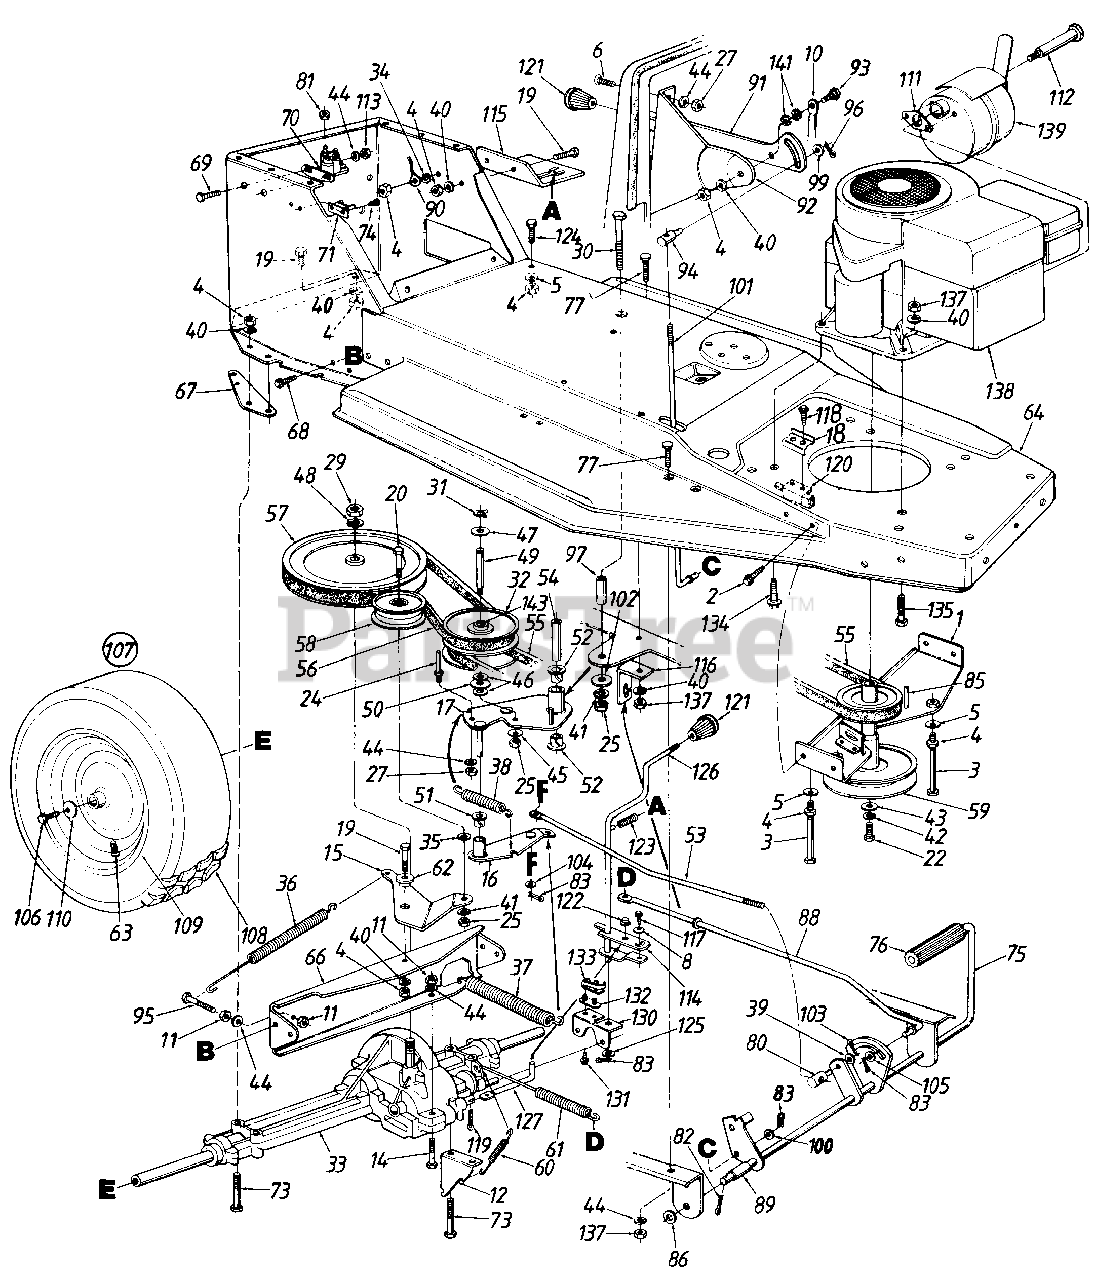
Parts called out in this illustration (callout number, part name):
1	Engine Pulley Belt Guard Ass'y.
2	Hex AB-Tap Scr. 1/4 x .62"
3	Hex Bolt 5/16-18 x 51/4" Lg.
4	Hex Nut 5/16-18 Thd.
5	Bell-Wash. .345" I.D. x .88
6	Truss-Mach. Scr. 1/4-20 x .50" Lg.
8	Bell-Wash. .265" I.D. x .75
10	Speed Selector Brace
11	Hex Nut 1/4-28 Thd.*
12	Spring Retainer Brkt.
14	Hex Bolt 1/4-28 x 1.75" Lg.
17	Variable Speed Brkt. Ass'y.
18	Switch Plate
19	Hex Bolt 5/16-18 x .75" Lg.
20	Hex Bolt 3/8-24 x 2.0" Lg. Grade 5
22	Hex Bolt 7/16-20 x 1.5" Lg.
24	Belt Guard Pin
25	Hex Nut 3/8-24 Thd.
27	Hex Nut 1/4-20 Thd.
29	Hex Jam Nut 1/2-20 Thd.
30	Hex Bolt 3/8-24 x 3.75" Lg.
31	Snap Ring
32	Variable Speed Pulley Ass'y.
33	Transaxle Complete
34	Ext. L-Wash. 5/16" I.D.
35	Fl-Wash. 3/8" I.D. x 1.0" O.D.
36	Extension Spring 6.12" Lg.
37	Extension Spring 7.5" Lg.
38	Extension Spring 2 69" Lg.
39	Fl-Wash. 885" I.D. x .620"
40	L-Wash. 5/16" I.D.
41	L-Wash. 8/8" I.D.
42	L-Wash. 7/16" I.D.
43	Fl-Wash. .450" I.D. x 1.25"
44	L-Wash. 1/4" I.D.
45	Bell-Wash. .39" I.D. x 1.13"
46	Fl-Wash. 56" I.D. x 1.0" O.D.
47	Washer "Teflon" .565 I.D.
48	Bell-Wash. 1/2" I.D. x 1.0" O.D.
49	Shaft .56" Dia. x 8 .375" Lg.
50	Thrust Brg. 1.25 O.D.
51	Flanged Nyliner Brg.
52	Nyliner Flanged Brg.
53	Speed Control Rod
54	Spacer
55	V-Belt
56	V-Belt
57	V-Pulley
58	Idler Pulley 3-1/8" Dia.
59	Dbl. Pulley 6.0" Dia. x 3.56"
60	Extension Spring 3.18" Lg.
61	Extension Spring 7.08" Lg.
62	Shld. Spacer .500" Dia.
63	Air Valve
66	Transaxle Support Brkt.
69	Hex Bolt 1/4-20 x .62" Lg.
70	Solenoid
71	Circuit Breaker
73	Hex Bolt 5/16-18 x 2.75" Lg.
74	Truss Mach. B-Tap Scr. #10 x.50" Lg.
75	Foot Pedal Rod Ass'y.
76	Foot Pad
77	Ribbed Neck Bolt 5/16-24 x .84" Lg.
80	Ferrule
81	Hex Sems Nut 1/4-20 Thd.
82	Cot-Pin 1/8" Dia. x 1.25" Lg.
83	Cot-Pin 3/32" Dia. x .75" Lg.
85	Sq. Key 1/4 x 2.0" Lg.
86	Fl-Wash. .635" I.D. x 1.0"
88	Brake Rod
89	Spacer 5/8" I.D. x 1.2" Lg.
90	Ground Wire 7.25" Lg.
91	Speed Selector Lever
92	5 Speed Selector Brkt.
93	Shld. Bolt .437" Dia. x .47" Lg.
94	Ferrule
95	Hex Bolt 1/4-28 x 1.25" Lg.
96	Intern. Cot-Pin 5/16" Dia.
97	Spacer .375" I.D. x .625"
99	Fl-Wash. .344" I.D. x .62"
100	Fl-Wash. .25" I.D. x .62" O.D.
101	Speed Control Rod
102	Fl-Wash. 3/8" I.D. x .1" O.D.
103	Cot-Pin 1/8" Dia. x 1.0" Lg.
104	Fl-Wash. .34" I.D. x .68"
105	Fl-Wash. .34" I.D.
106	Hex L-Bolt 5/16-24 x .75" Lg.
107	Rear Wheel Ass'y. Comp.
110	Bell-Wash. .345" I.D. x .88"
113	Hex Jam Nut 1/4-20 Thd.
114	Shift Lever Adjusting Link
115	Shift Lever Spring Brkt.
118	Hex B-Tap Scr. #10 x .38" Lg.
119	Intern. Cotter Pin
120	Safety Switch
121	Knob
122	Retaining Ring
123	Compression Spring 1.5" Lg.
124	Hex Wash. Hd. Scr. 5/16-18 x .62" Lg.
125	Fl-Wash. .469" I.D. x .88"
130	Shift Lever Support
131	Hex Wash. Hd. #8 x .50" Lg.
132	Insulator Nut Plate
133	Spring Switch
134	Hex Wash. Hd. Tap Scr. 3/8-16 x 1.25" Lg.
135	Hex Bolt 5/16-24 x 1-1/4" Lg. Grade 5
137	Hex Nut 5/16-24 Thd.
138	Engine
139	Muffler
141	Wave Wash. .445" I.D.
143	Needle Brg.
